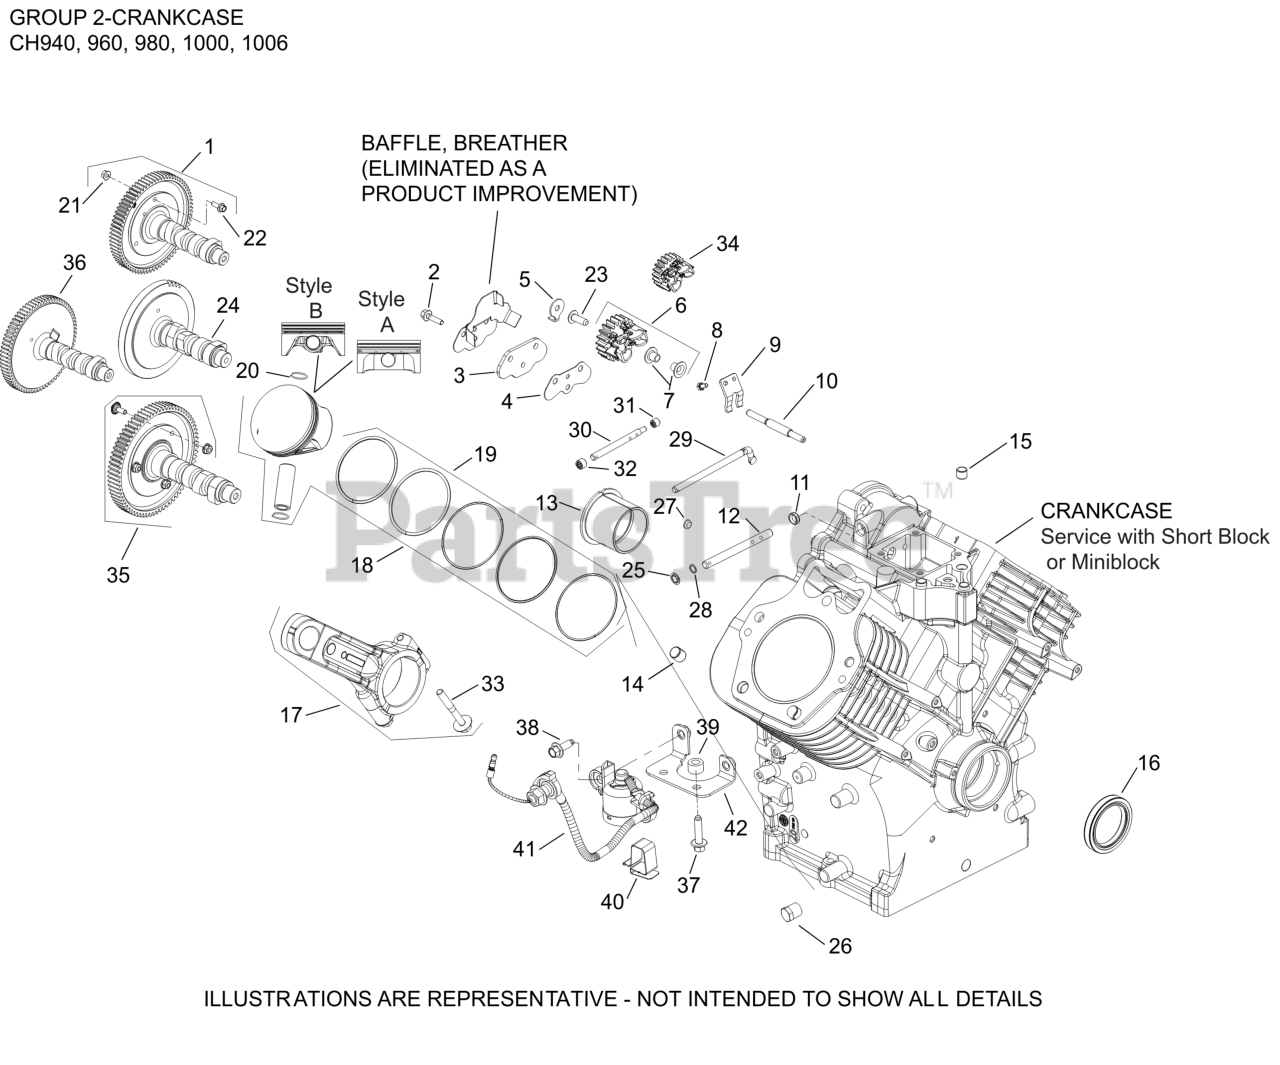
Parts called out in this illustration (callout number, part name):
2	SCREW, HEAVY HEX FLANGE
3	KIT, COVER, LIFTER FEED
4	GASKET, LIFTER FEED COVER
14	PIN, LOCATING
16	SEAL, OIL (RIGHT-HAND HELIX, FWE)
17	CONNECTING ROD ASSEMBLY
18	KIT, PISTON (STD)
18	KIT, PISTON (0.25 OS)
18	KIT, PISTON (0.50 OS)
19	RING, SET PISTON (STD) "STYLE B ONLY"
20	RETAINER, PISTON PIN
24	KIT, CAMSHAFT
33	KIT, ROD BOLTS
37	SCREW, FLG M6X1.0X25
38	SCREW, HEX FLANGE (M6 W/DOG POINT)
40	CLIP, BLOWER HOUSING
41	SWITCH, OIL SENSOR ASSEMBLY
42	BRACKET, SWITCH OIL SENSOR
